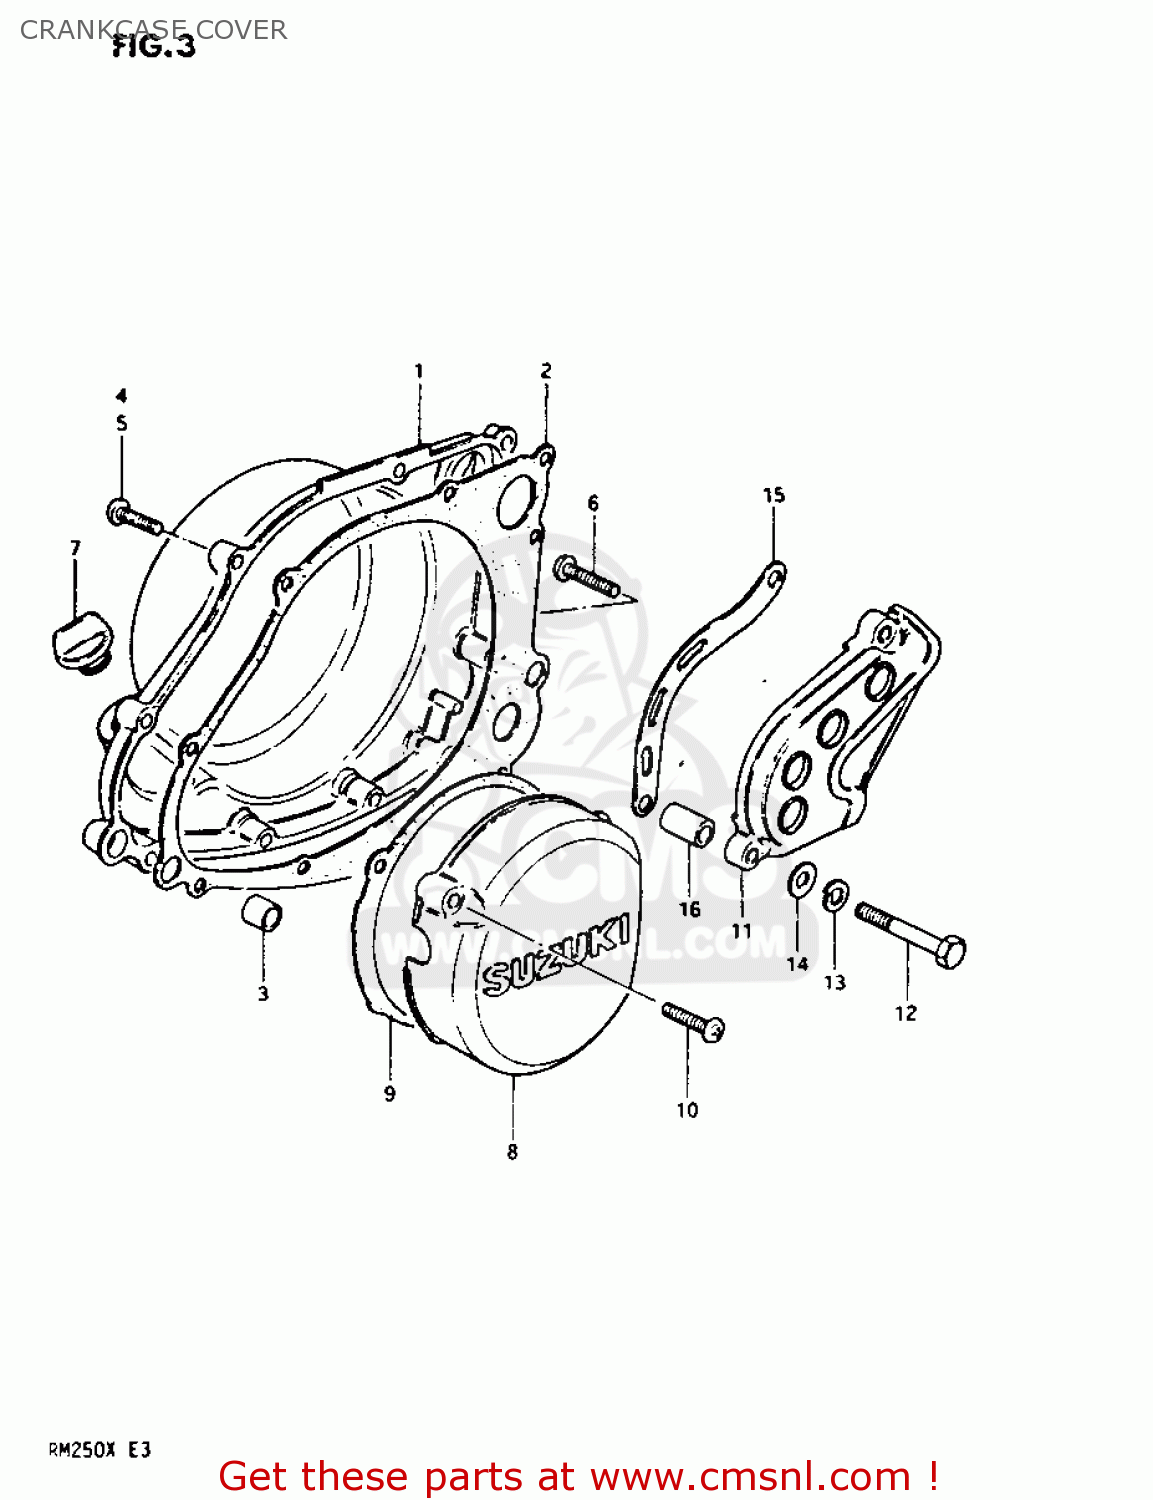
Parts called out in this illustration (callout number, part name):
1	COVER,CLUTCH
2	GASKET,CLUTCH COVER (NAS)
3	PIN
4	SCREW
5	SCREW 6X30
6	SCREW
7	PLUG SET
8	COVER,MAGNETO
9	GASKET,MAGNETO COVER (NAS)
10	SCREW
11	COVER,ENGINE SPROCKET
12	BOLT 8X55
13	LOCK WASHER
14	WASHER
15	PLATE,FR CHAIN GUIDE
16	SPACER(8.6X16X24)
